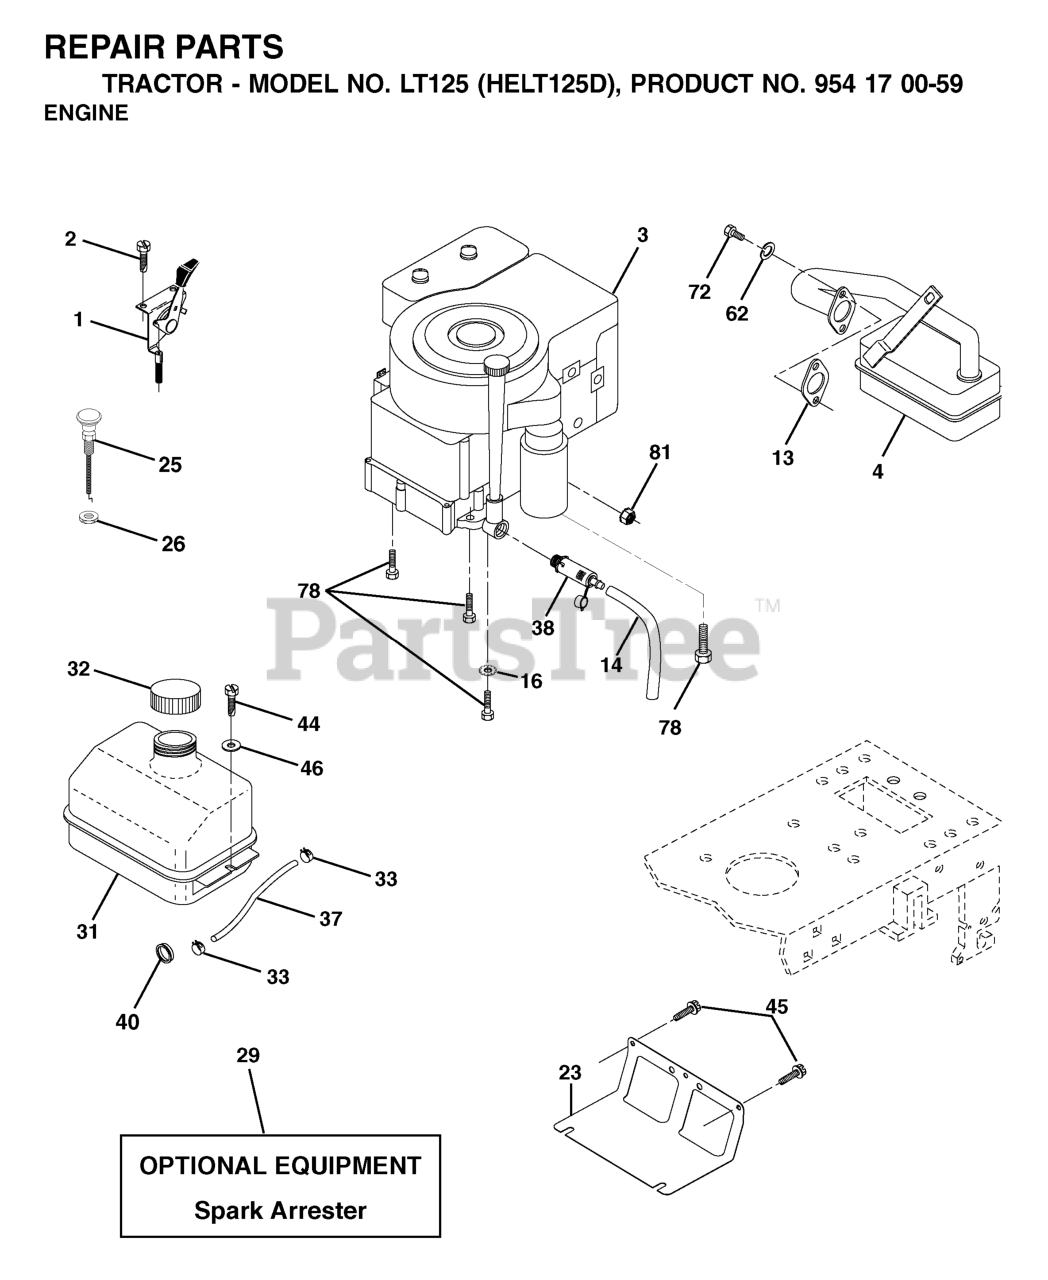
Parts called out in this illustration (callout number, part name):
1	CONTROL.THROTTLE/CHOKE.BLACK
2	SCREW
4	MUFFLER.SINGLE.B&S.10-12HP
13	REPL BY 532 27 22-93
14	TUBE, DRAIN OIL ASM.
16	LOCKWASHER
23	SHIELD.BROWNING.DBR.GUARD
26	Nut Keps 3/8 - 24 UNF
29	KIT.SPARK ARRESTOR 794945 B&S
31	TANK FUEL LT
32	FUEL CAP
33	HOSE CLAMP
37	LINE.FUEL.20
38	PLUG, OIL DRAIN EASY
40	BUSHING.SNAP.NYL.BLK.
44	SCREW HEXWSHR 1/4-20X3/4
45	SCREW, 3/8-16X3/4
62	WASHER.LOCK.HVY.HLCL.SPR.5/16
72	SCREW
78	SCREW.3/8-16
81	NUT
